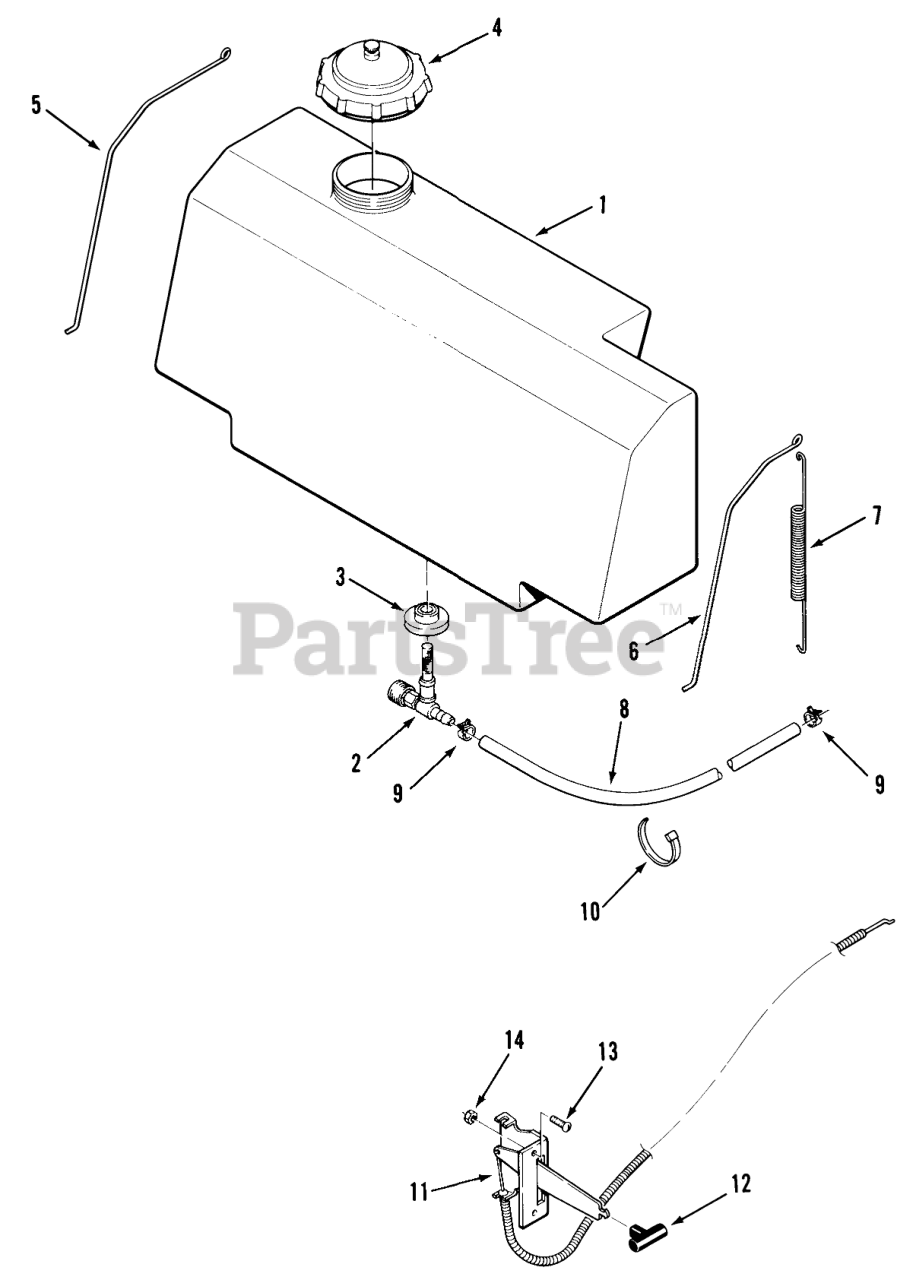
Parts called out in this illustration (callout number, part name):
1	FUEL TANK ASSY
2	Valve
3	BUSHING
4	ASSY FUEL CAP
5	RETAINER TANK RH
6	RETAINER TANK LH
7	SPRING EXTENSION
8	Hose
9	Clamp
10	PLASTIC TIE
11	CONTROL-THROTTLE
12	KNOB-CONTROL
13	Screw
14	Nut
